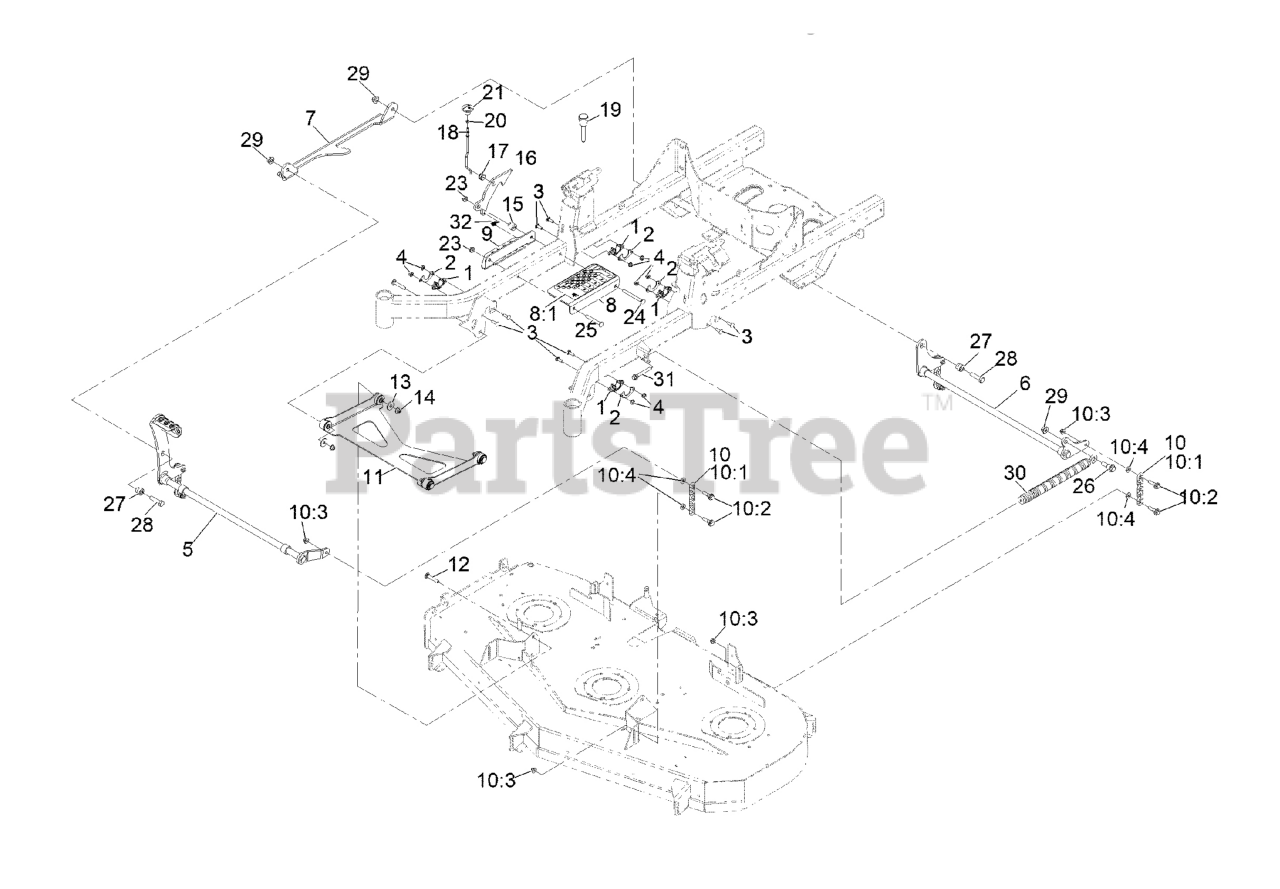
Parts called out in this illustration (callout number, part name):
1	BEARING-FLANGE
2	GUSSET-LIFT, DECK
3	SCREW-CARR
4	NUT-HF, NI
5	SHAFT-DECKLIFT FRONT
6	SHAFT-DECKLIFT REAR
7	LINK-DECKLIFT
8	BRACKET ASM
8:1	DECAL-HOC
9	Plate, HOC Lower
10	DECK CHAIN ASM
10:1	CHAIN-LIFT, DECK
10:2	BOLT-SHOULDER
10:3	NUT-HF, NI
11	DECK STRUT ASM
12	BOLT-CARR, SHORT NECK
14	Nut-Nyloc 3/8-16 Flg
15	SPACER-STEPPED
16	LATCH, TRANSPORT
17	GROMMET
18	LINKAGE, TRANSPORT
19	PIN-HOC
20	NUT-JAM
23	NUT-HF, NI
24	SCREW-CARR
25	SCREW-CARR
26	SCREW-SHOULDER HHF
27	SPACER, HOC
28	SCREW-HEX
29	NUT-HF, NI
30	SPRING-EXTENSION
31	BOLT-SHOULDER
32	SPRING, EXTENSION
